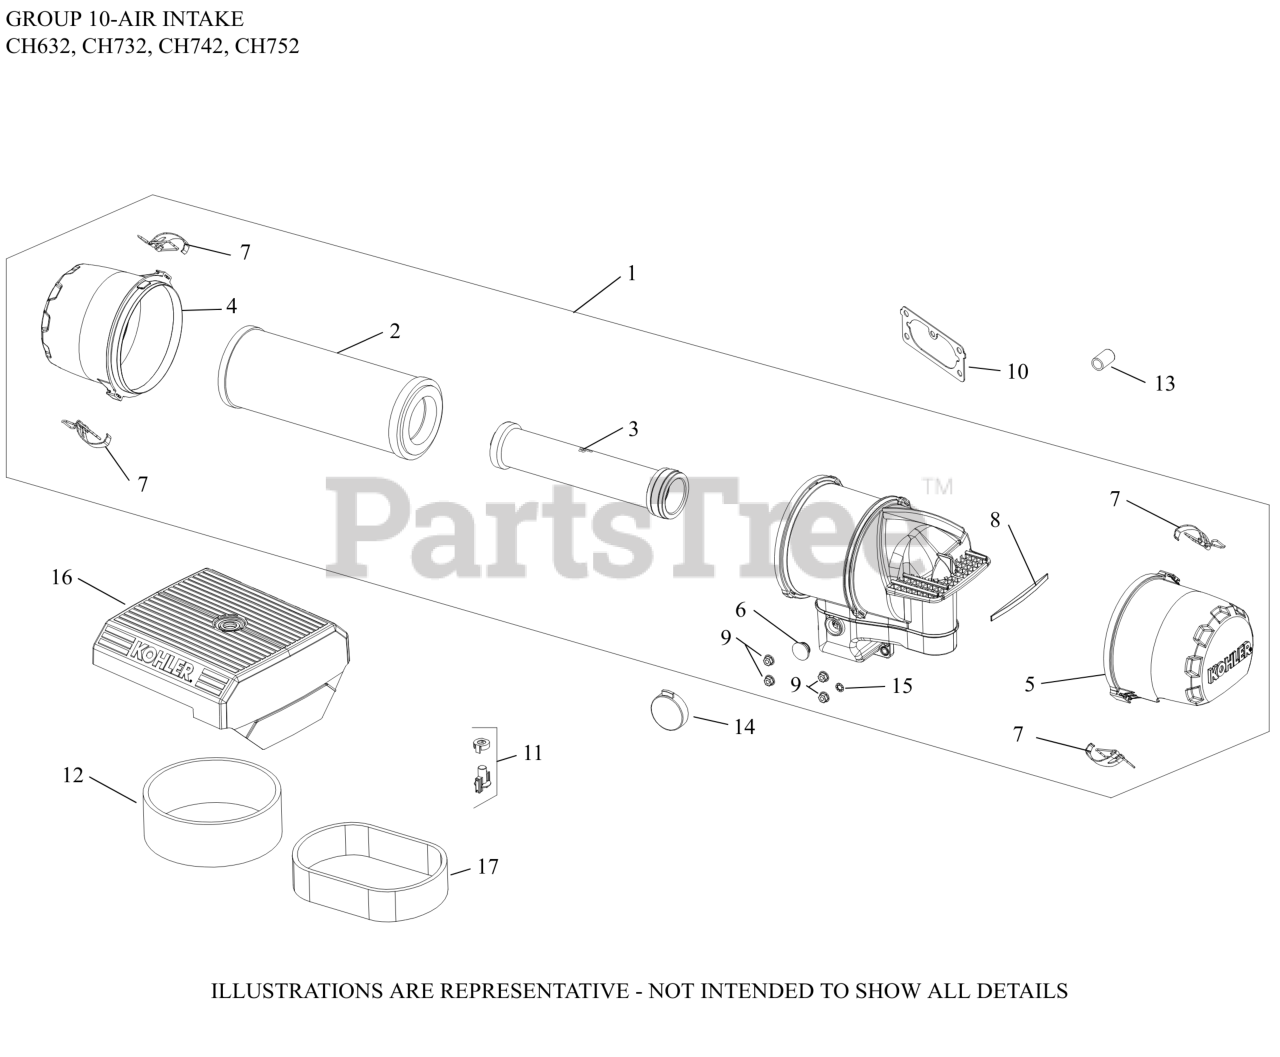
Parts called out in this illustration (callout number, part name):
1	KIT, AIR CLEANER
2	ELEMENT, AIR FILTER - PRIMARY
3	ELEMENT, AIR FILTER - SAFETY
4	COVER, AIR FILTER
5	COVER, RAIN CAP
6	PLUG, HOLE
7	CLIP ASSEMBLY
8	DAMPER, FOAM INSERT
9	NUT, FLG M6X1.0
10	GASKET, AIR CLEANER
15	WASHER, INT TOOTH LOCK 1/4"
